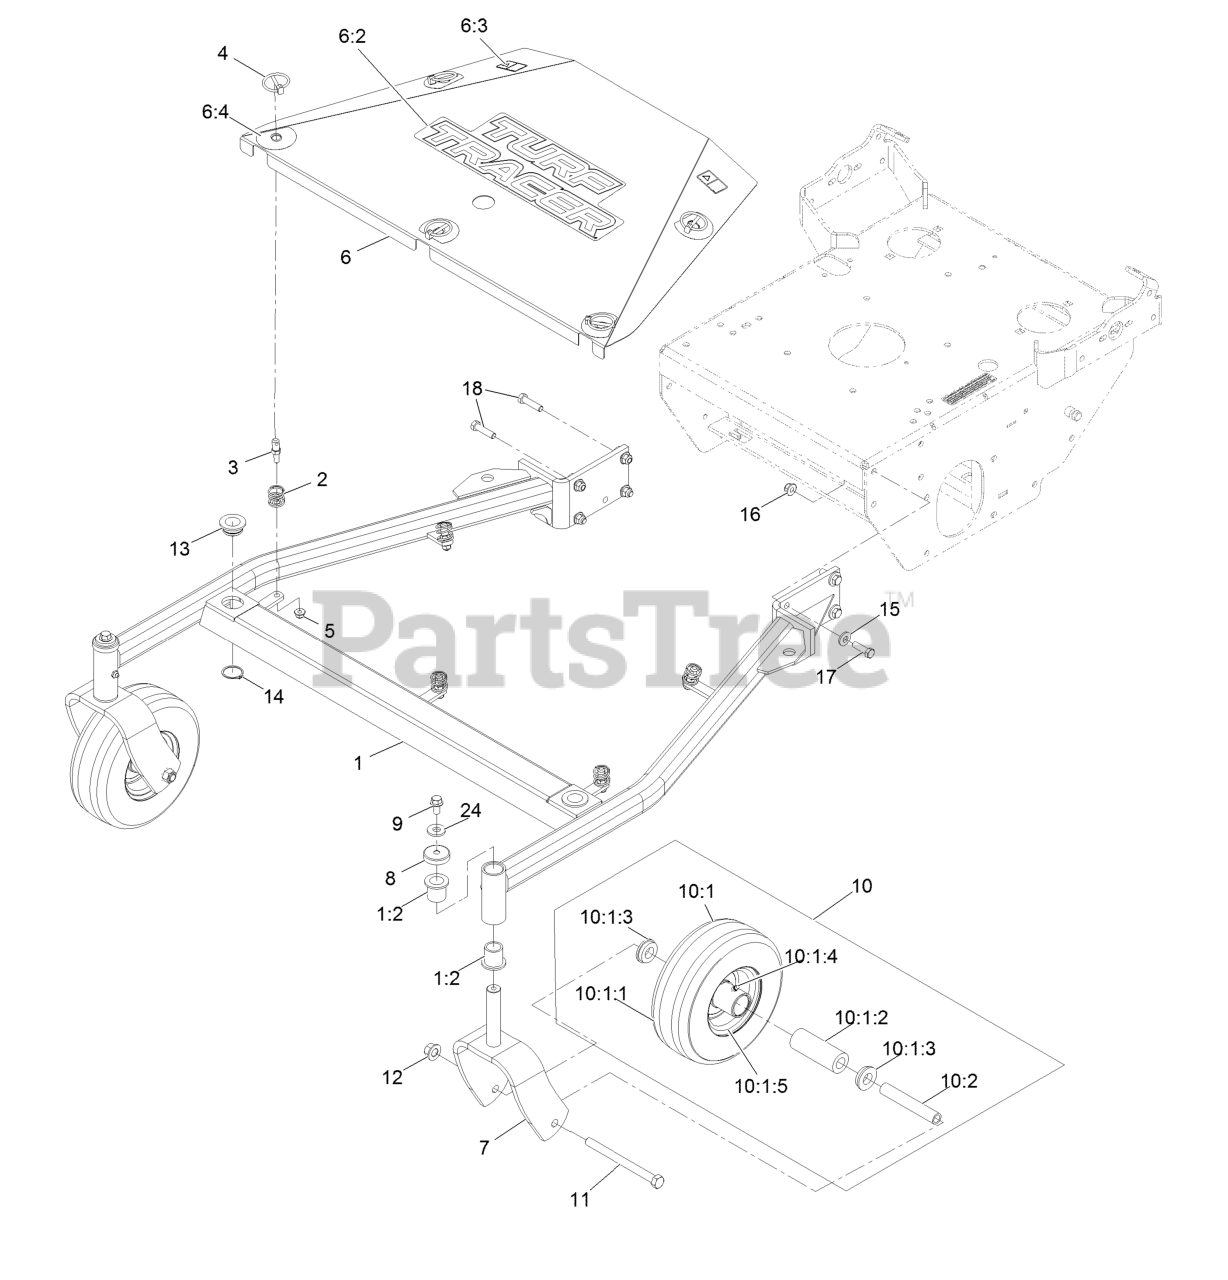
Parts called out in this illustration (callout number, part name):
1	ASM, Frame W/ Bushings,48
1:2	Bearing-Flanged
3	Pin-Spring
4	Pin-Lynch
5	Nut-Nyloc 5/16-18 Flg
6	ASM, Shield W/ Decals, 48
6:2	Decal-Turf Tracer
6:3	Decal-Warning
6:4	Decal-Scratch Cover
7	Fork, Caster [red]
8	Cap, Dust
9	Screw-Hex Flange 3/8-16 X 3/4
10	Kit,Semi-Pneumatic Wheel Replacement
10:1	Wheel And Tire ASM
10:1:1	Tire
10:1:2	Bearing
10:1:3	Bushing-Flanged
10:1:4	Zerk-45deg 1/4-28
10:1:5	Wheel
11	Screw-HH 1/2-13 X 6
12	Nut-Lock 1/2-13
13	Bushing-Deck
14	Ring-Retaining
15	Washer-Spring Disc 3/8
16	Nut-Nyloc 3/8-16 Flg
17	Screw-HH 3/8-16 X 1 1/4
18	Screw-HH 3/8-16 X 1 1/2
